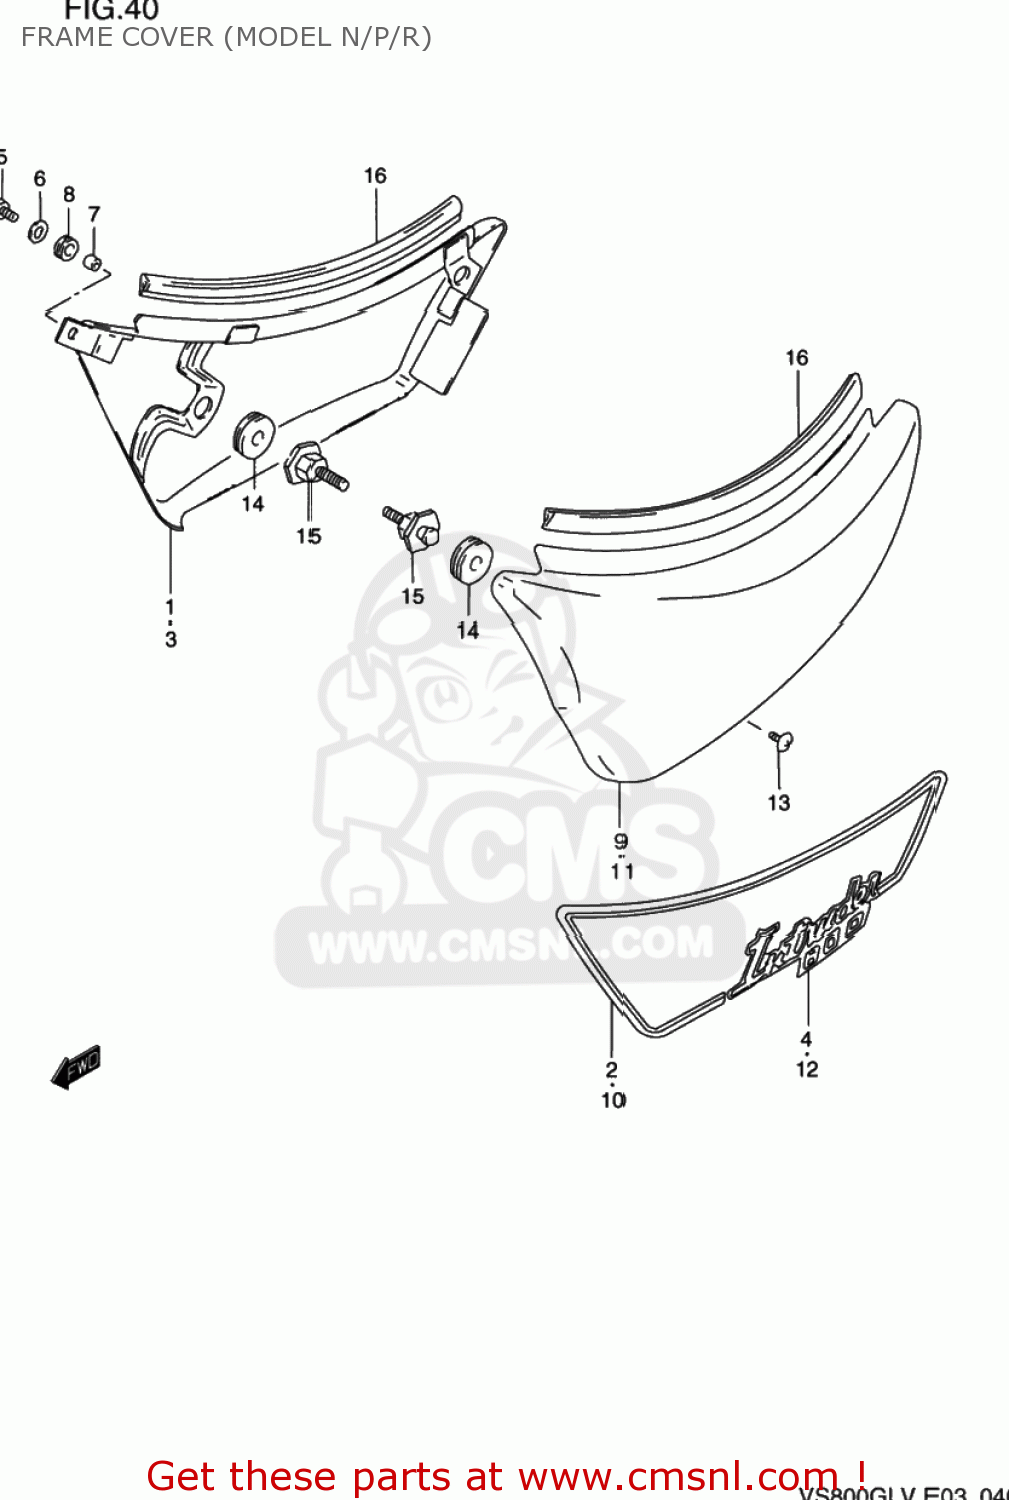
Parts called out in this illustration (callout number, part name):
1	COVER ASSEMBLY,FRAME,RIGHT
2	TAPE,FRAME COVER,RIGHT
3	COVER ASSEMBLY,FRAME,RIGHT
4	EMBLEM,FRAME COVER
5	BOLT
6	WASHER(6.5X18X1.6)
7	SPACER (6.1X8X5.2)
8	CUSHION
9	COVER ASSEMBLY,FRAME,LEFT
10	TAPE,FRAME COVER,LEFT
11	COVER ASSEMBLY,FRAME,LEFT
12	EMBLEM,FRAME COVER
13	SCREW
14	CUSHION
15	BOSS,FRAME COVER
16	MOLDING, FRAME COVER
